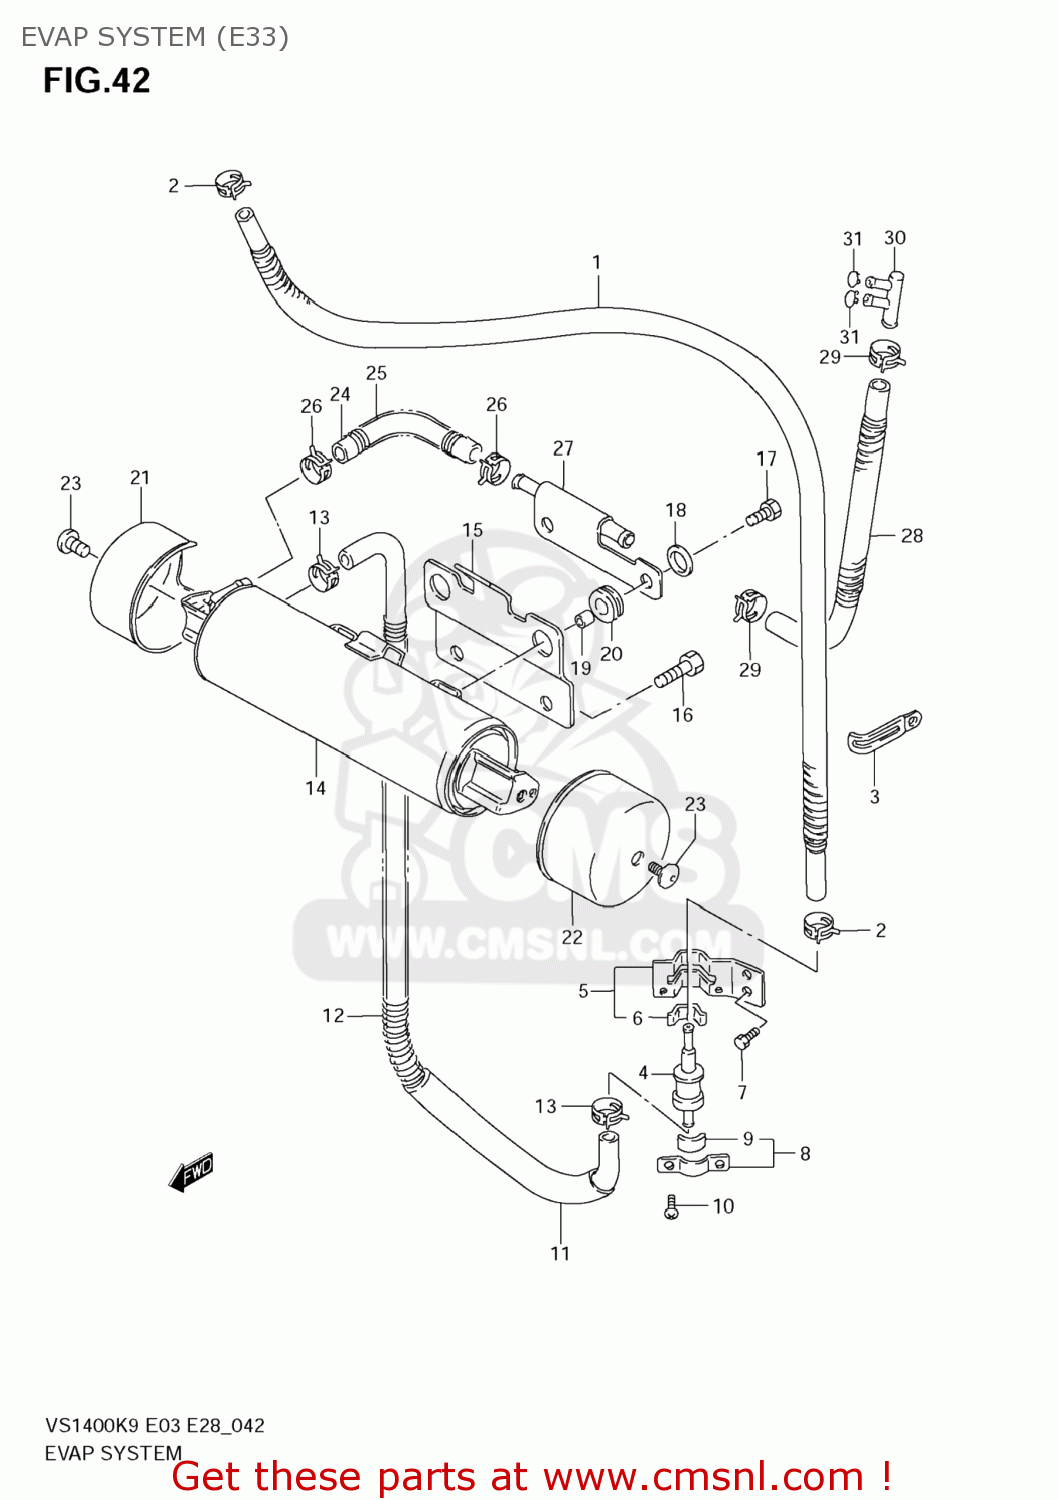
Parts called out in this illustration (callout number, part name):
1	HOSE,JOINT FUEL TANK
2	CLIP
3	CLAMP(L:80)
4	VALVE,FUEL TANK BREATHER
5	BRACKET,TANK BRTHR VALVE
6	CUSHION
7	BOLT
8	PLATE,FUEL TANK BREATHER NO.2
9	CUSHION
10	SCREW
11	HOSE,VALVE & CANISTER JOINT
12	SPRING
13	CLIP
14	CANISTER ASSY,CHARCORL
15	PLATE,CANISTER FITING
16	BOLT
17	BOLT
18	WASHER(6.5X22X1.6)
19	SPACER(6.1X9X7.5)
20	CUSHION
21	COVER,CANISTER
22	COVER,CANISTER
23	SCREW(6X10)
24	HOSE,CSTR PIPE JOINT
25	SPRING
26	CLIP
27	PIPE,CANISTER
28	HOSE,PIPE JOINT
29	CLIP
30	SEPARATOR
31	CLIP
